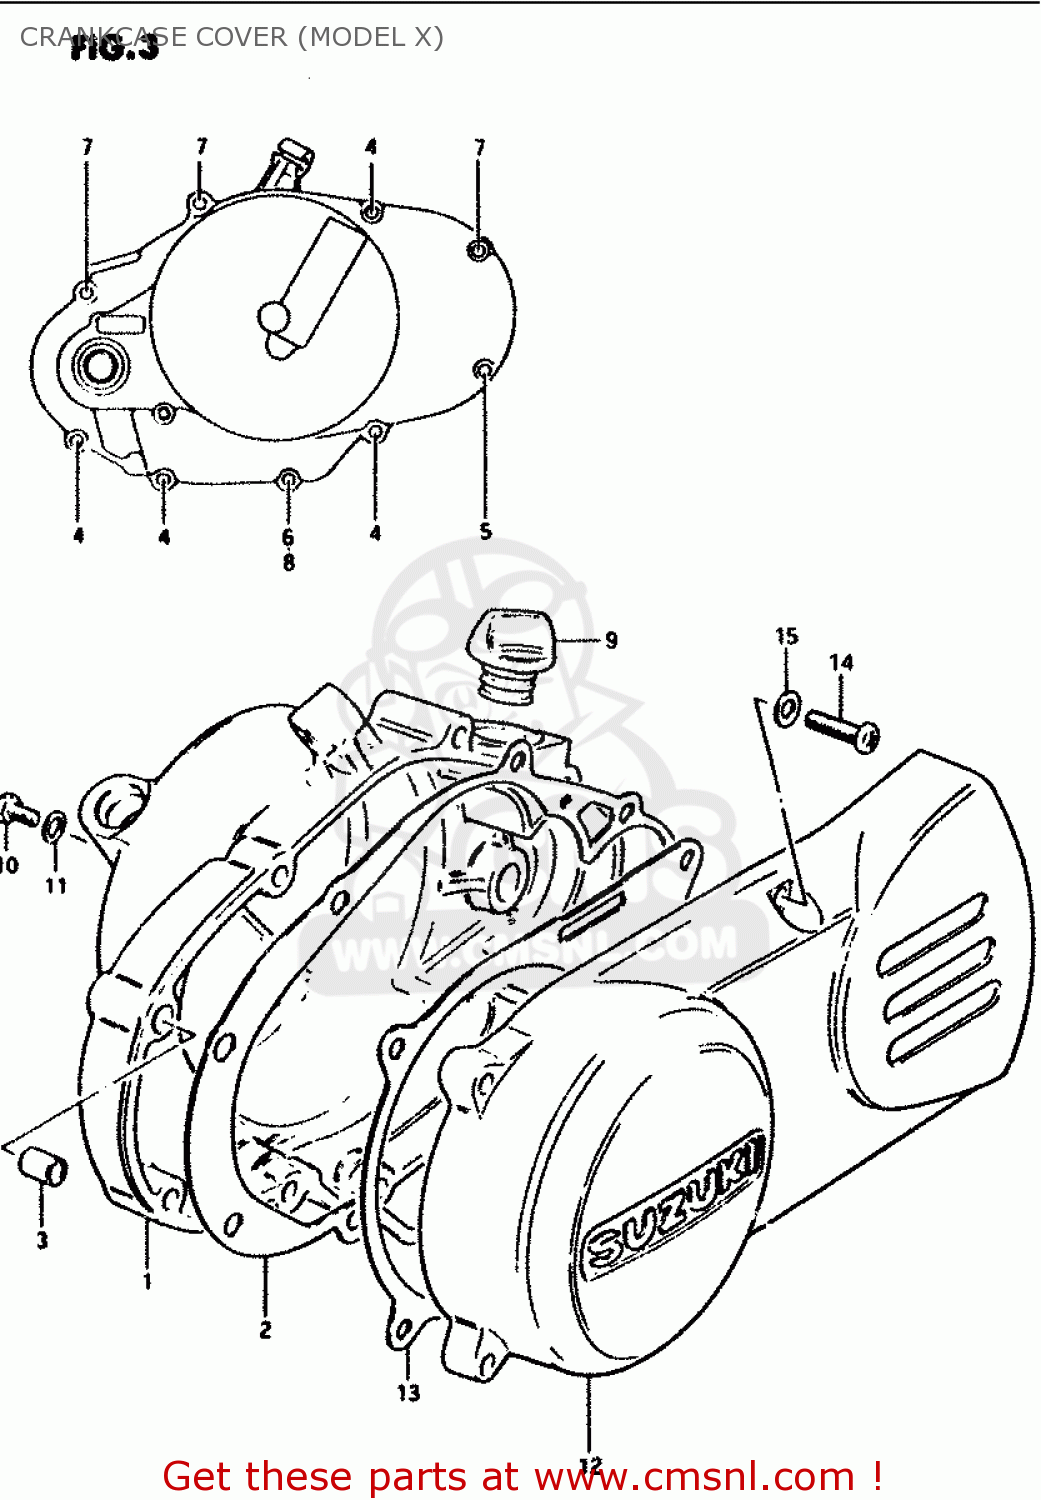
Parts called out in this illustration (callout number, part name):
1	COVER,CLUTCH
2	GASKET,CLUTCH COVER (MCA)
3	PIN
4	SCREW
5	SCREW 6X30
6	SCREW
7	SCREW
8	GASKET(6.2X11X1).2 (NAS)
9	PLUG
10	SCREW(6X10)
11	GASKET(6.2X11X1) (NAS)
12	COVER,MAGNETO
13	GASKET,MAGNETO COVER (NAS)
14	SCREW
15	WASHER
